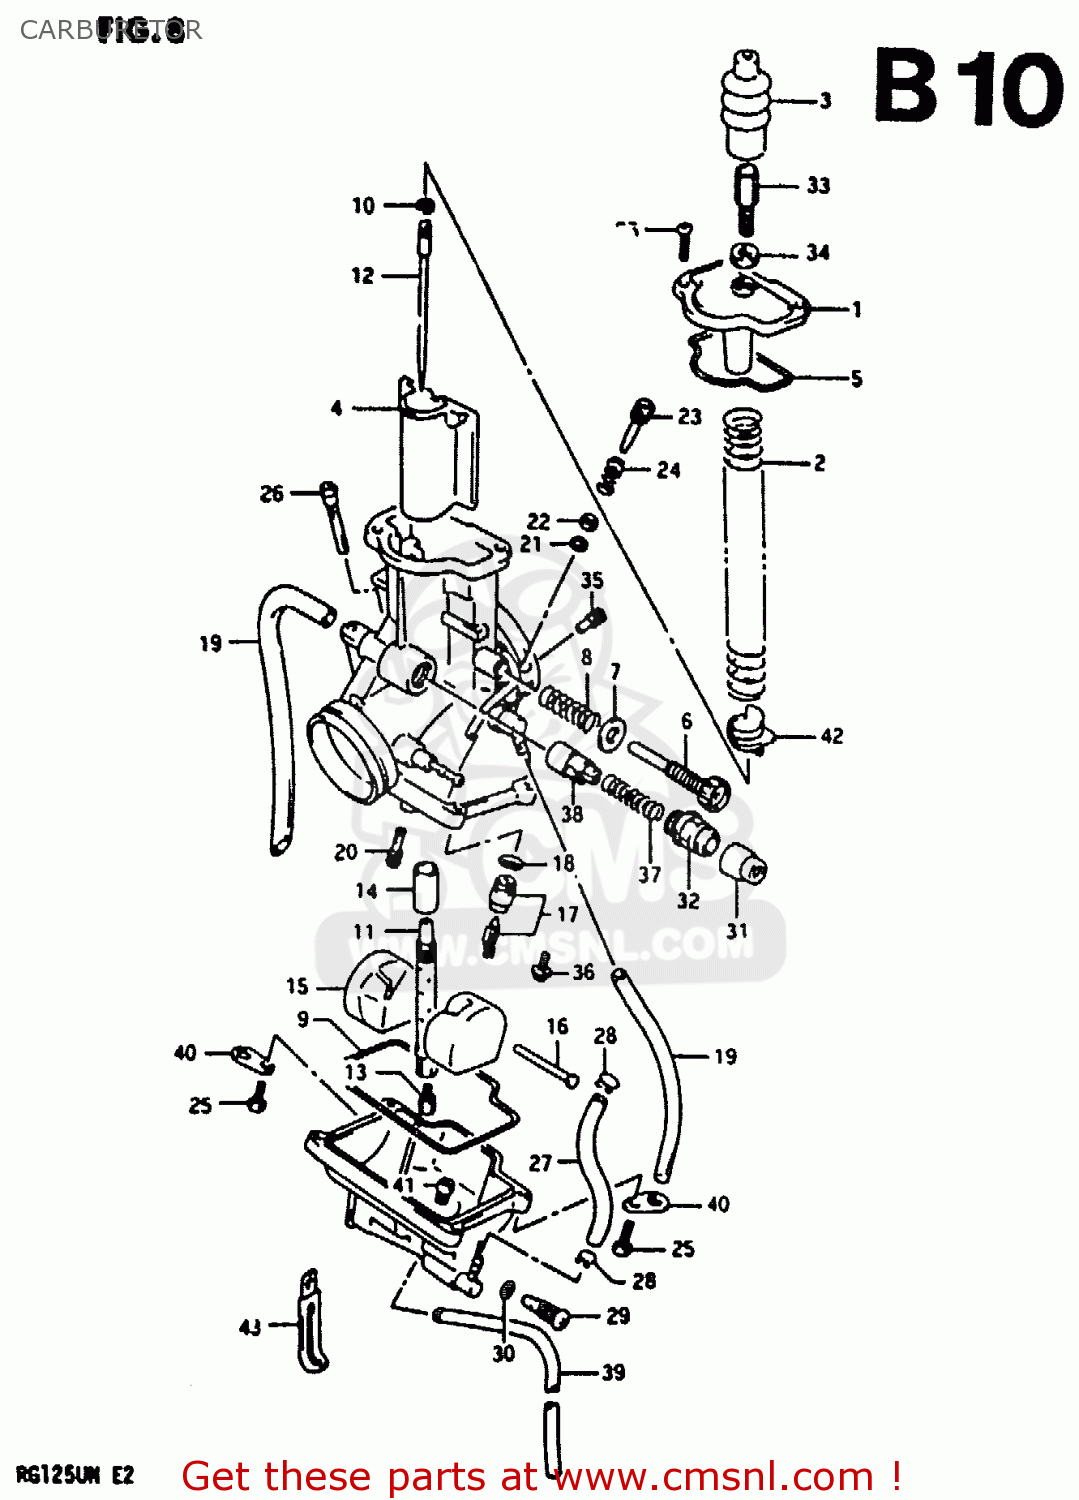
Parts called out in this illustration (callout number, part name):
1	CAP, TOP
2	SPRING
3	CAP,CABLE ADJUSTER
4	VALVE,PISTON(CA:1.5)
5	O RING,TOP CAP
6	ADJUSTER
7	WASHER
8	SPRING
9	GASKET,FLOAT CAHMBER (NAS)
10	CLIP,NEEDLE
11	JET,NEEDLE(P-3)
12	NEEDLE,JET
13	JET,MAIN(195)
14	RING
15	FLOAT
16	PIN,FLOAT
17	VALVE ASSY,NEEDLE
18	O-RING,NEEDLE VALVE
19	HOSE
20	JET,PILOT(27.5)
21	O RING,PILOT AIR SCREW
22	WASHER
23	SCREW,PILOT AIR
24	SPRING,THROTTLE SCREW
25	SCREW
26	FILTER
27	HOSE SET
28	CLIP
29	PLUG,DRAIN
30	O RING
31	CAP
32	HOLDER,GUIDE
33	ADJUSTER,CABLE
34	NUT
35	JET,AIR(0.6)
36	SCREW
37	SPRING
38	PLUNGER,STARTER
39	HOSE
40	PLATE,CARBURETOR
41	JET
42	RING
43	CLAMP
